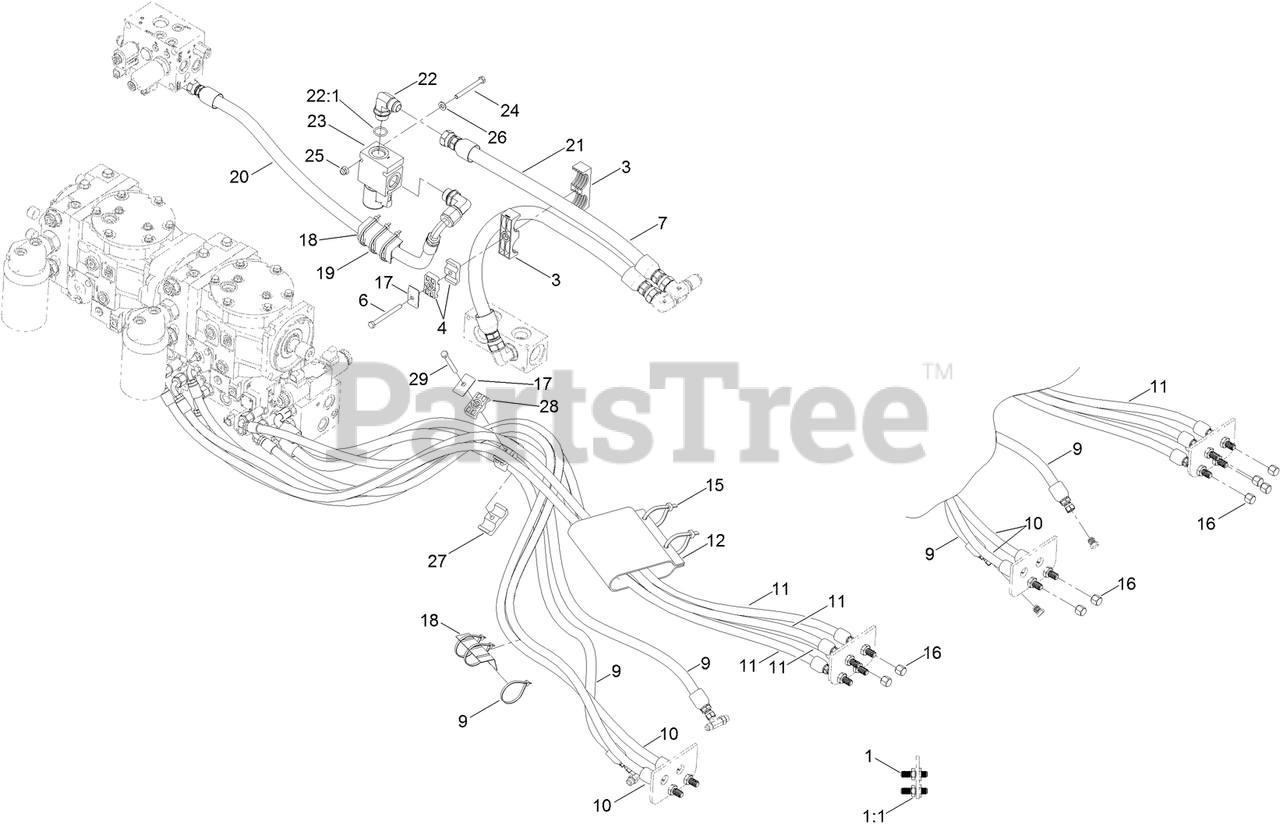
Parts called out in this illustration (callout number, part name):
1	UNION-BULKHEAD
1:1	NUT-LOCK, BULKHEAD
3	CLAMP-TWIN
4	CLAMP-TUBE
6	SCREW-HH
7	HYD HOSE ASM
9	HYD HOSE ASM
10	HYD HOSE ASM
11	HYD HOSE ASM
12	BOOT-HOSE
15	TIE-CABLE
17	COVERPLATE
18	PROTECTOR-HOSE
19	TIE-CABLE
20	HYD HOSE ASM
21	HYD HOSE ASM
22	FITTING-ELBOW, 90 DEG
22:1	O-RING
23	VALVE-BLOCKING
24	SCREW-HH
25	NUT-LOCK, HHF
26	WASHER-PLAIN
27	CLAMP-TUBE
28	CLAMP-TUBE
29	SCREW-HH
